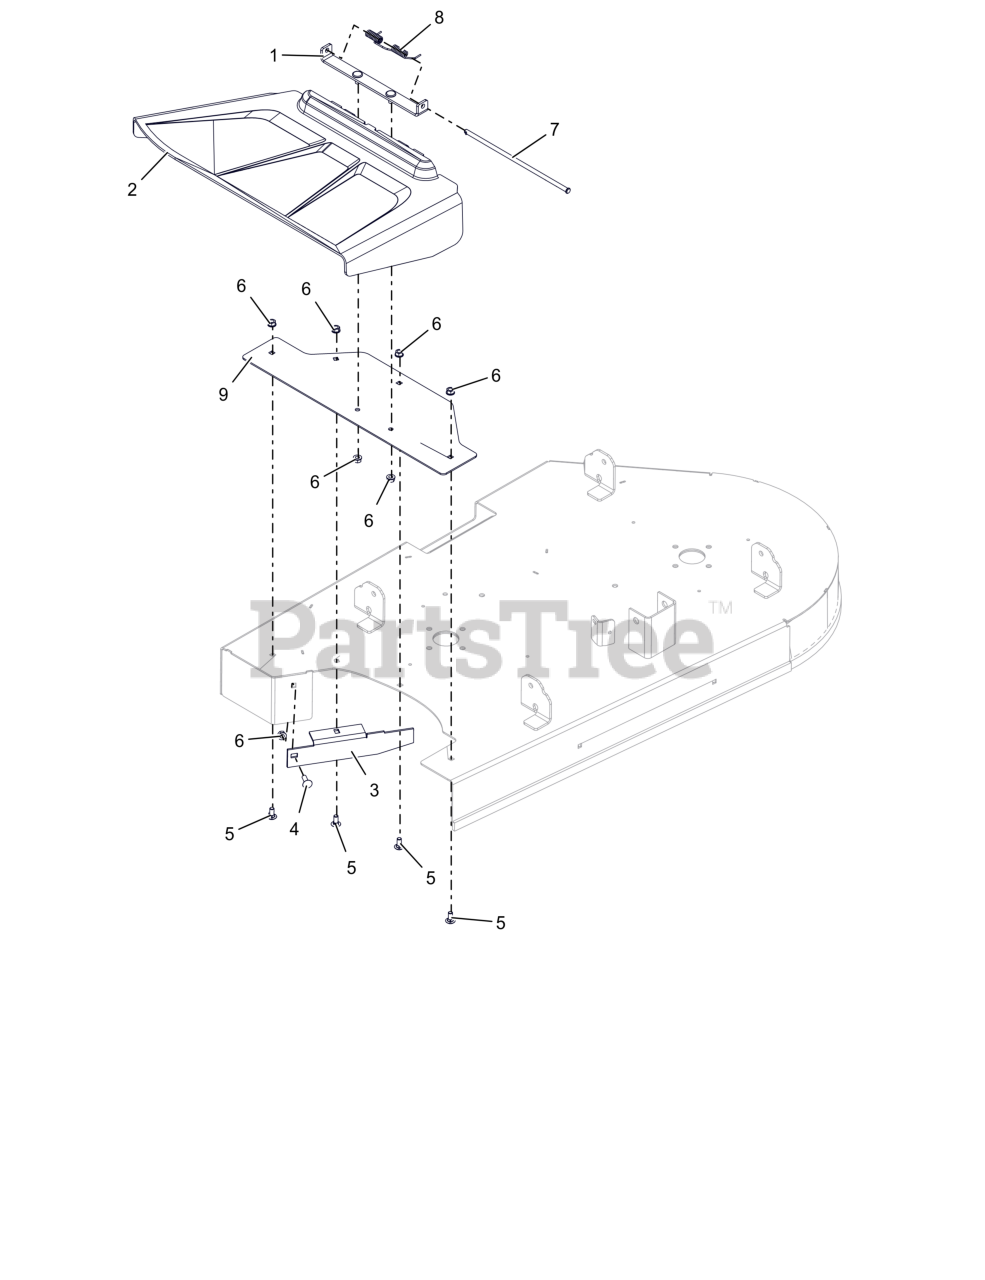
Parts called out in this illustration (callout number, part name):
2	CHUTE, SIDE DISCHARGE
3	STRIP- DEFLECTOR
4	BLT,RHSN .31-18X1.00 G5 ZCC
5	BLT,RHSN .31-18X.75 G5 ZCC
6	NUT,LK-CTR-FLG .31-18 GF ZCC
7	PIN, SLIC-.312X10.45
8	SPRING-TORSION
9	PLATE, DECK - DISCHARGE (ORANGE)
